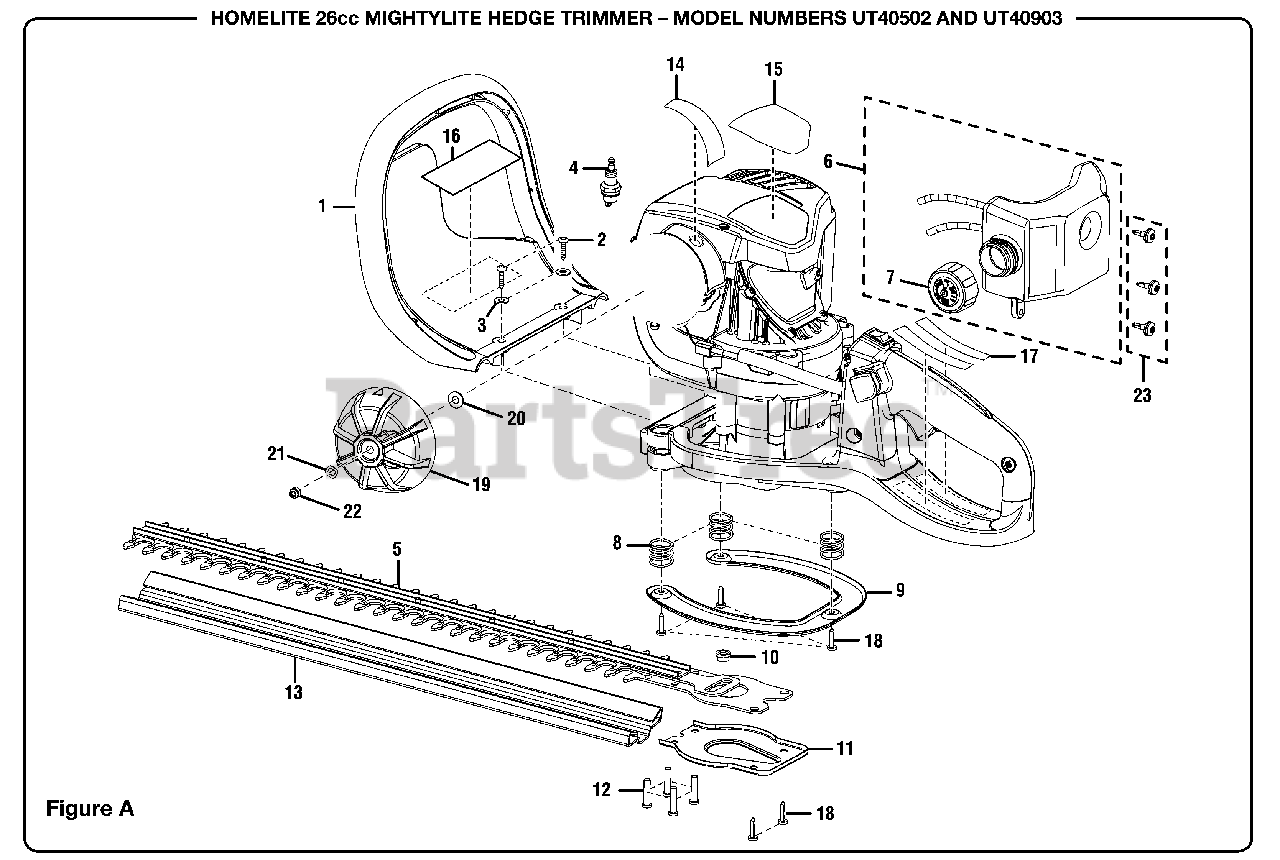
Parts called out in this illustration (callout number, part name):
1	Front Handle
2	Screw (M5 x 25 mm)
3	Flat Washer (M5)
4	Spark Plug
5	Blade Assembly
6	Fuel Tank with Cap Assembly
11	Gear Box Cover
12	Screw (M5 x 24 mm)
14	Choke Label
15	Logo Label
16	Warning Label
17	Starting Label
18	Screw (M5 x 17 mm)
19	Roto-Choke Cover
20	Flat Washer
21	Wavy Washer
22	Lock Nut (M4)
23	Screw (M4 x 10 mm, Shoulder)
